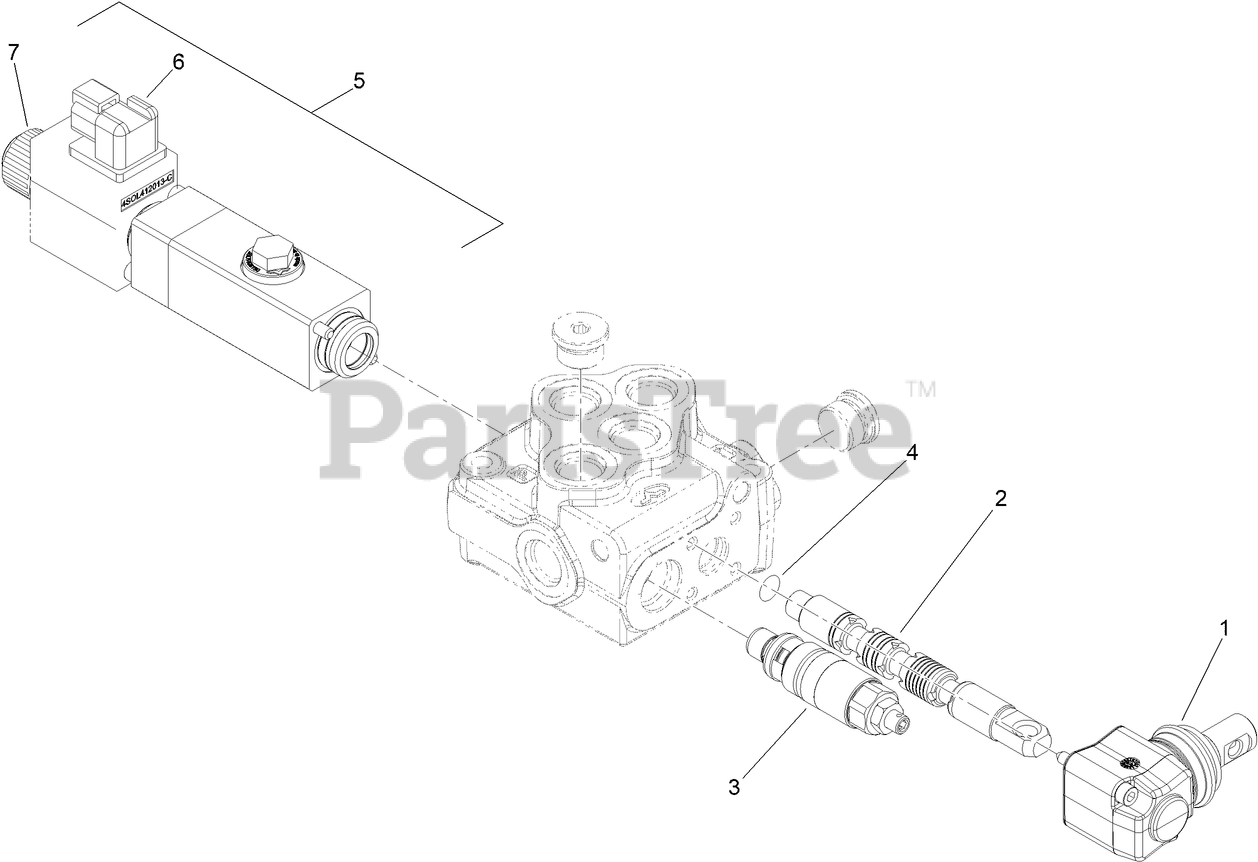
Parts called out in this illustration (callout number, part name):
1	LEVER KIT (WITH SCREWS)
2	SPOOL-VALVE
3	VALVE-RELIEF
4	SEAL-VALVE
5	KIT-VALVE, SPRING/COIL ASM
6	COIL-VALVE
7	PULL TUBE, VALVE
